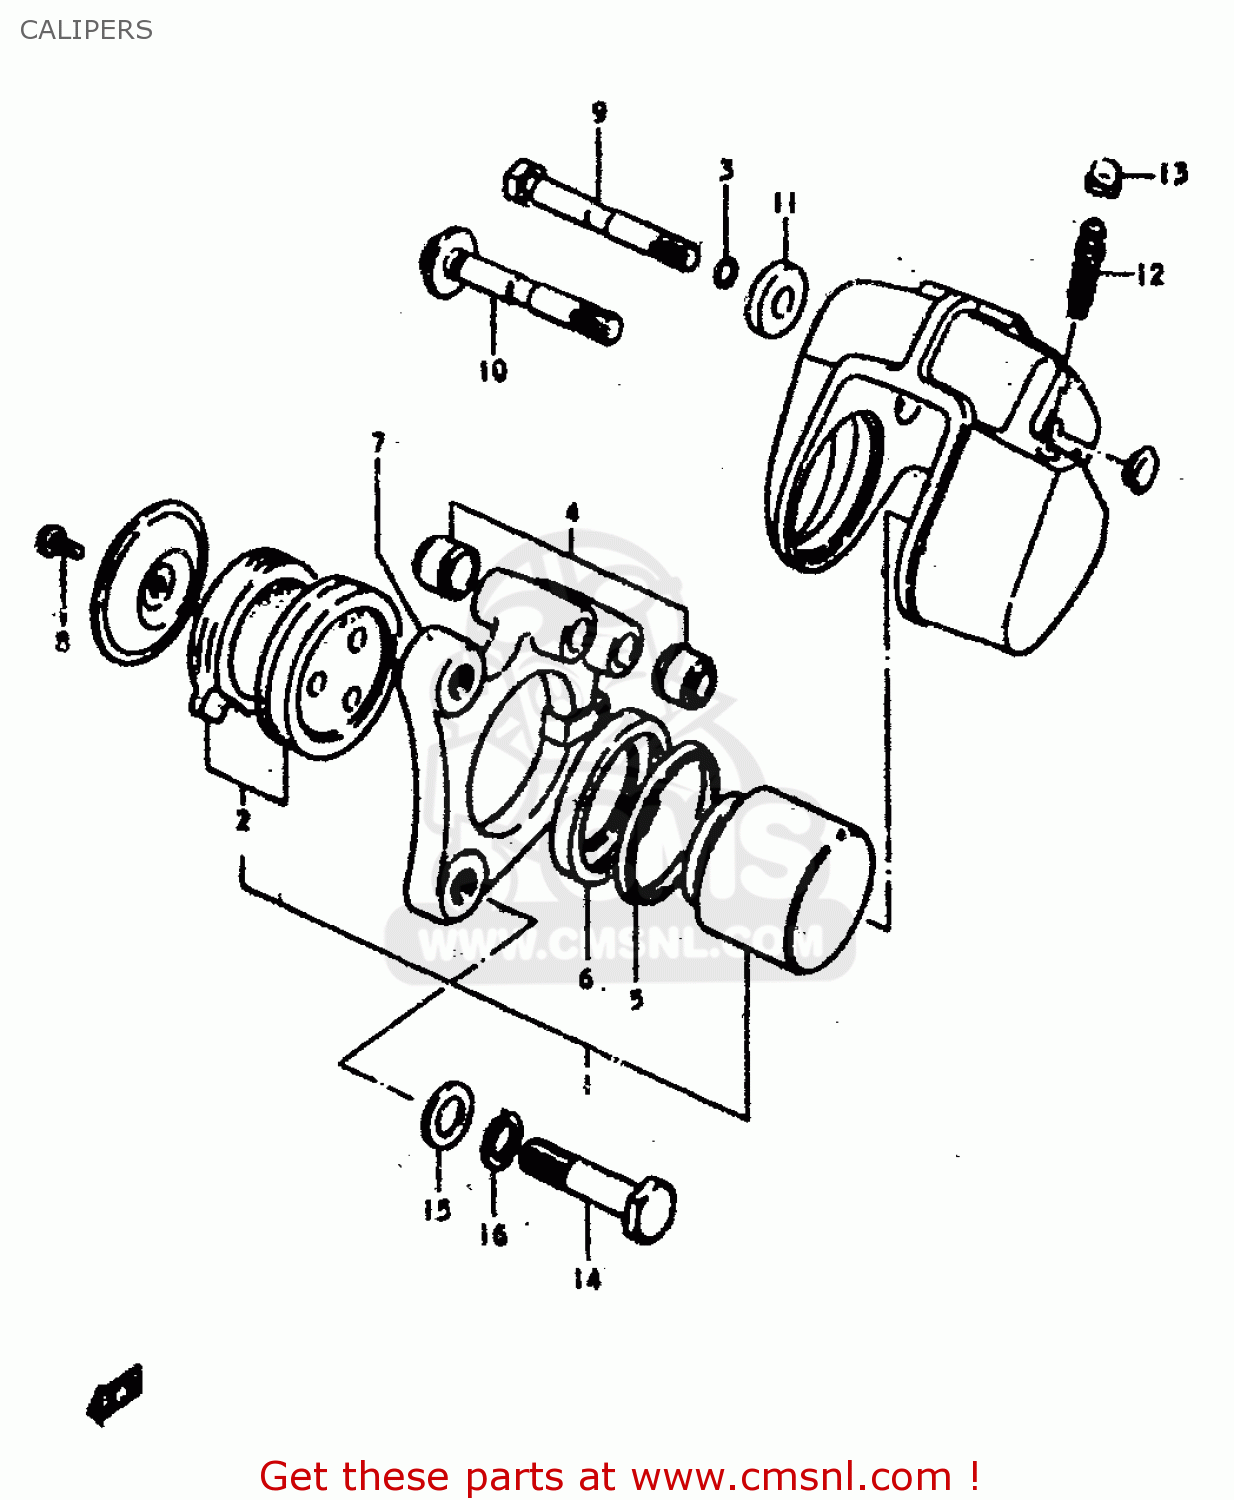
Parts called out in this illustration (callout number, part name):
1	PAD SET
2	CARRIER,CALIPER,LEFT
3	O RING
4	COVER,AXLE DUST
5	SEAL,FR CALIPE
6	BOOT,PISTON
7	HOLDER, CARIPERS LH
8	SCREW 6X12
10	AXLE,CALIPER
12	BLEEDER
13	CAP,BREATHER
14	BOLT
15	WASHER
16	LOCK WASHER
